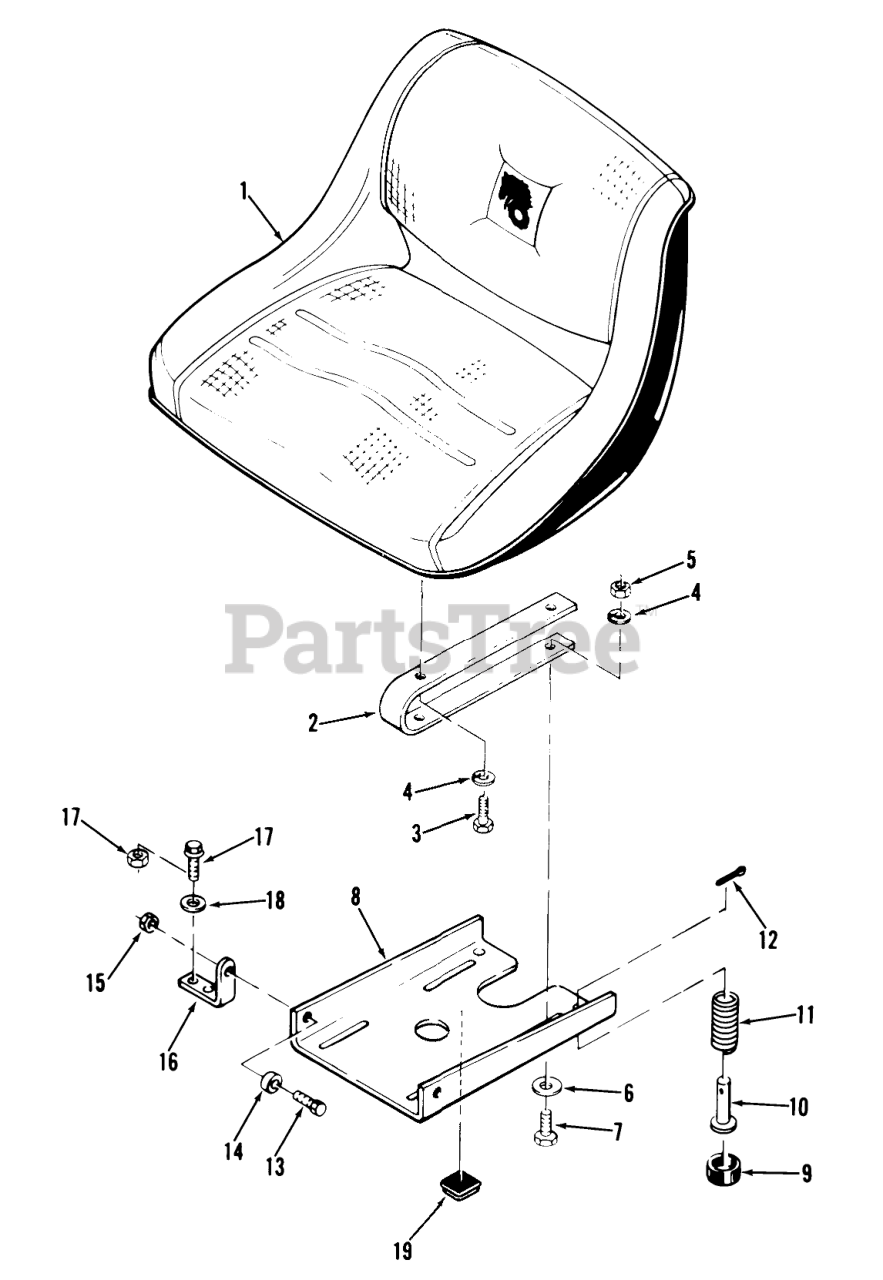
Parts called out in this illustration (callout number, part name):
1	Seat
2	Spring
3	Bolt
4	Lockwasher
5	Nut
6	WASHER 5/16 SAE
7	HHCS
8	Plate-Seat Pivot
11	SPRING
12	Cotter Pin
13	HHCS
14	BUSHING
15	Nut
16	BRACKET-PIVOT
17	SEAT BOLT FOR C195
18	WASHER 5/16 SAE
19	BUMPER
